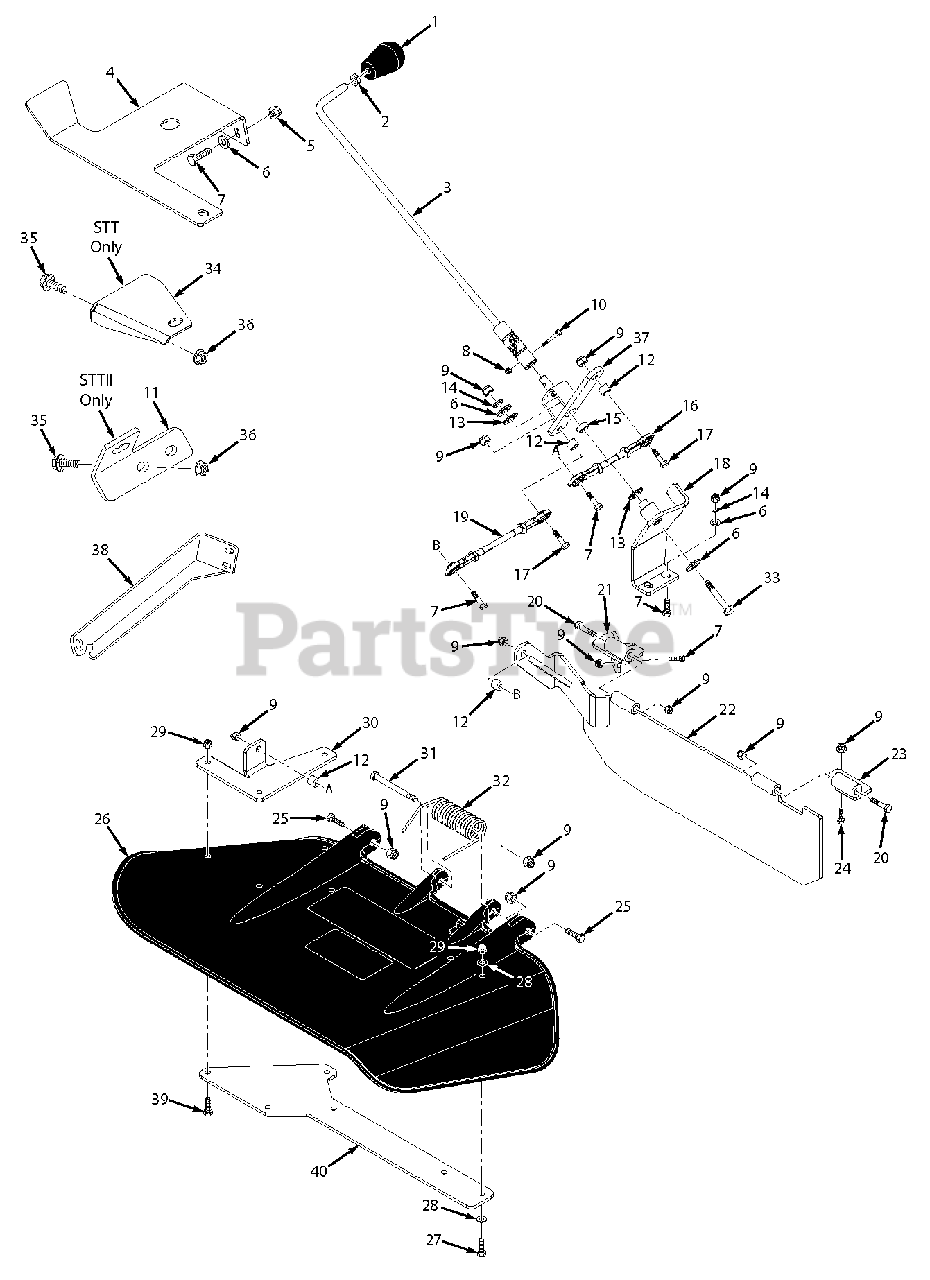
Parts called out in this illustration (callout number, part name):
1	Knob, Soft Touch
2	Nut, 3/8-16 UNC Jam
3	Lever Weldment, OCDC (STC/STCII/SCZ & STT/STTII)
3	Lever Weldment, OCDC (SVR)
4	Bracket, Lever Support (STC-48V & 52V)
4	Bracket, Lever Support (STCII/SCZ-48V & 52V)
4	Bracket, Lever Support (STC-61V)
4	Bracket, Lever Support (STCII-61V)
4	Bracket, Lever Support (SCZ-61V)
5	Nut, Serrated Flange 5/16-18
6	Flatwasher, 5/16-.375 x .875 x .083
7	Bolt, Hex Head 5/16-18 x 1"
8	Nut, Elastic Stop #8-32
9	Nut, Elastic Stop 5/16-18
10	Capscrew, Socket Head #8-32 x 1-1/4"
11	Guide Bracket, OCDC Lever (STTII)
12	Sleeve
13	Washer, Thrust 1/2" ID
14	Lockwasher, 5/16" Spring
15	Bearing
16	Linkage Assembly (SVR-48V)
16	Linkage Assembly (STC/STCII/SCZ/SVR-52V)
16	Linkage Assembly (STC/STCII/SCZ-48V & STT/STTII-52V)
16	Linkage Assembly (STC/STCII/SVR-61V)
16	Linkage Assembly (SCZ/STT/STTII-61V)
17	Bolt, Hex Head 5/16-18 x 1-1/2"
18	Pivot Weldment (SVR-48V & STC/STCII/SVR/SCZ/STT/STTII-52V)
18	Pivot Weldment (STC/STCII/SCZ-48V)
18	Pivot Weldment (STC/STCII/SVR-61V)
18	Pivot Weldment (SCZ/STT/STTII-61V)
19	Linkage Assembly (SVR-48V)
19	Linkage Assembly (STC/STCII/SCZ-48V)
19	Linkage Assembly, (STC/STCII/SCZ/SVR-52V)
19	Linkage Assembly (STT/STTII-52V)
19	Linkage Assembly (STC/STCII/SVR-61V)
19	Linkage Assembly (SCZ/STT/STTII-61V)
20	Bolt, Hex Head 5/16-18 x 3-1/2"
21	Hinge Weldment, Rear (48V)
21	Hinge Weldment, Rear (52V & 61V)
22	Block-Off Plate Weldment (48V)
22	Block-Off Plate Weldment (52V)
22	Block-Off Plate Weldment (61V)
23	Hinge Weldment, Front
24	Bolt, Hex Head 5/16-18 x 3/4"
25	Bolt, Hex Head 5/16-18 x 1-3/4"
26	Discharge Chute Assy., 48V
26	Discharge Chute Assy., 52V
26	Discharge Chute Assy., STT-52V
26	Discharge Chute Assy., 61V
27	Bolt, Hex Head 1/4-20 x 3/4"
28	Flatwasher, 1/4-.312 x .750 x .065
29	Nut, Elastic Stop 1/4-20
30	Plate, Discharge Chute (48V)
30	Plate, Discharge Chute (52V)
30	Plate, Discharge Chute (STT/STTII-52V Only)
30	Plate, Discharge Chute (61V)
31	Bolt, Hex Head 5/16-18 x 4-3/4"
32	Spring, Discharge Chute
33	Bolt, Hex Head 5/16-18 x 2"
34	Guide Bracket, OCDC Lever (STT)
35	Bolt, 5/16-18 x 3/4" Serrated Flange
36	Nut, 5/16-18 Serrated Flange
37	Pivot Arm Weldment (SVR-48V/52V/61V, STC/STCII-52V/61V, SCZ-52V/61V, STT/STTII-52V/61V)
37	Pivot Arm Weldment (STC/STCII/SCZ-48V)
38	Bracket, Lever Support (SVR)
39	Bolt, Hex Head 1/4-20 x 1"
40	Chute Stiffener (48V)
40	Chute Stiffener (52V)
40	Chute Stiffener (61V)
